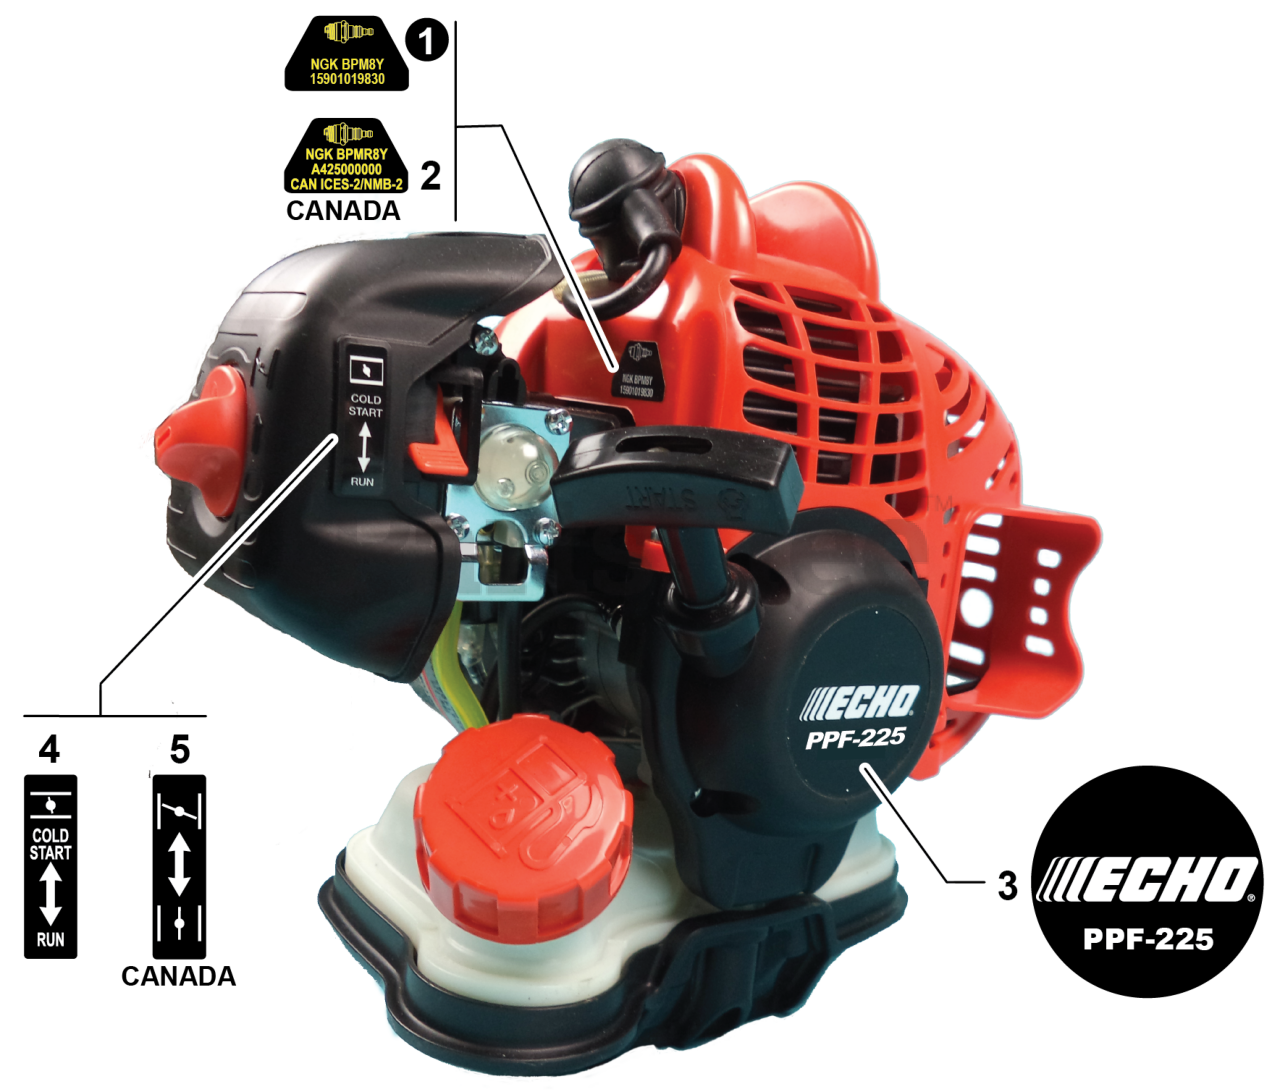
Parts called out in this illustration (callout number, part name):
1	LABEL - SPARK PLUG - BPM8Y
2	LABEL - SPARK PLUG - BPMR8Y
3	LABEL - STARTER - PPF-225
4	LABEL - CHOKE
5	LABEL - CHOKE
